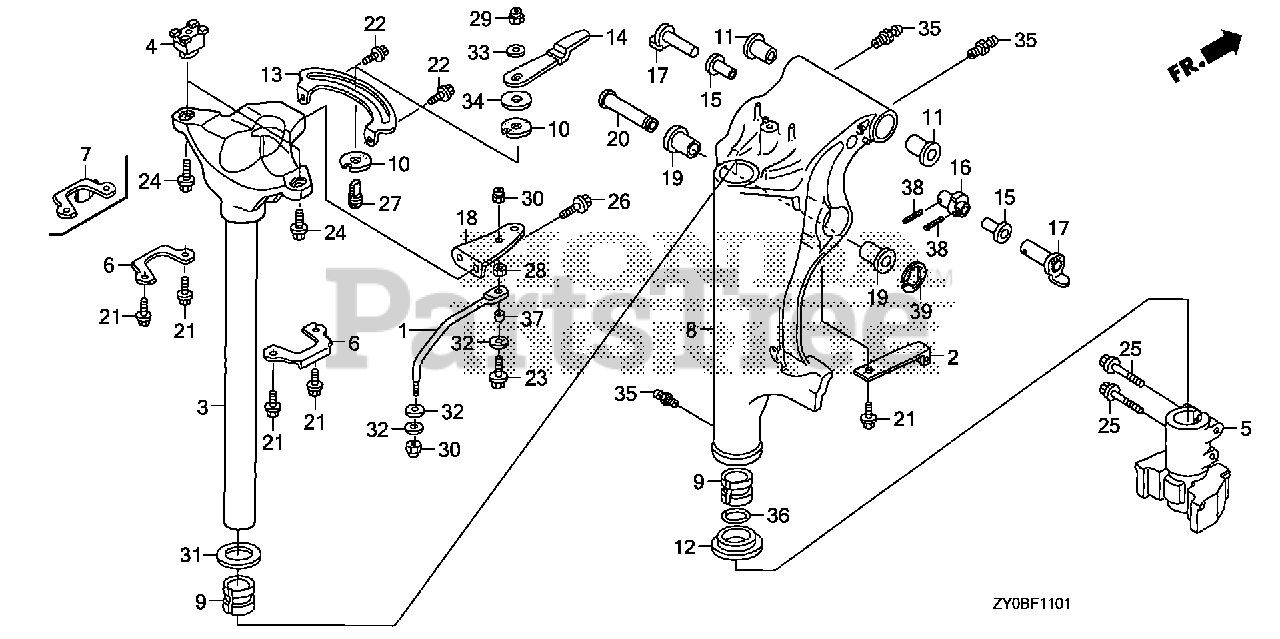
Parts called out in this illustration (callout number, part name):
2	SPRING, CLICK
3	FRAME, MOUNTING (S)
4	RUBBER, MOUNTING (UPPER)
5	RUBBER, MOUNTING (LOWER)
6	COVER, MOUNTING RUBBER (UPPER)
7	COVER, MOUNTING RUBBER (UPPER) (PT)
8	CASE, SWIVEL *NH282MU* (S)(PT) (OYSTER SILVER METALLIC-U)
9	LINER, SWIVEL CASE
10	BLOCK, FRICTION
11	BUSH, SWIVEL CASE
12	COLLAR, SWIVEL CASE
13	PLATE, FRICTION
14	LEVER, FRICTION
15	BUSH, TILT ARM
16	BRACKET, TILTING
17	STOPPER, TILT
19	BUSH, CYLINDER (LOWER)
20	PIN, CYLINDER (UPPER)
21	BOLT, FLANGE (6X12) Use from Frame SN 1005249.
22	BOLT, FLANGE (6X12)
24	BOLT, FLANGE (10X25)
25	BOLT, FLANGE (8X45)
27	BOLT, STUD (8X26)
29	NUT, SELF-LOCK (8MM)
31	WASHER, THRUST
33	WASHER (8MM)
34	WASHER, NYLON (8MM)
35	NIPPLE, GREASE
36	O-RING (34X2.4)
38	PIN, SPRING (2.5X20)
39	E-RING (15MM)
